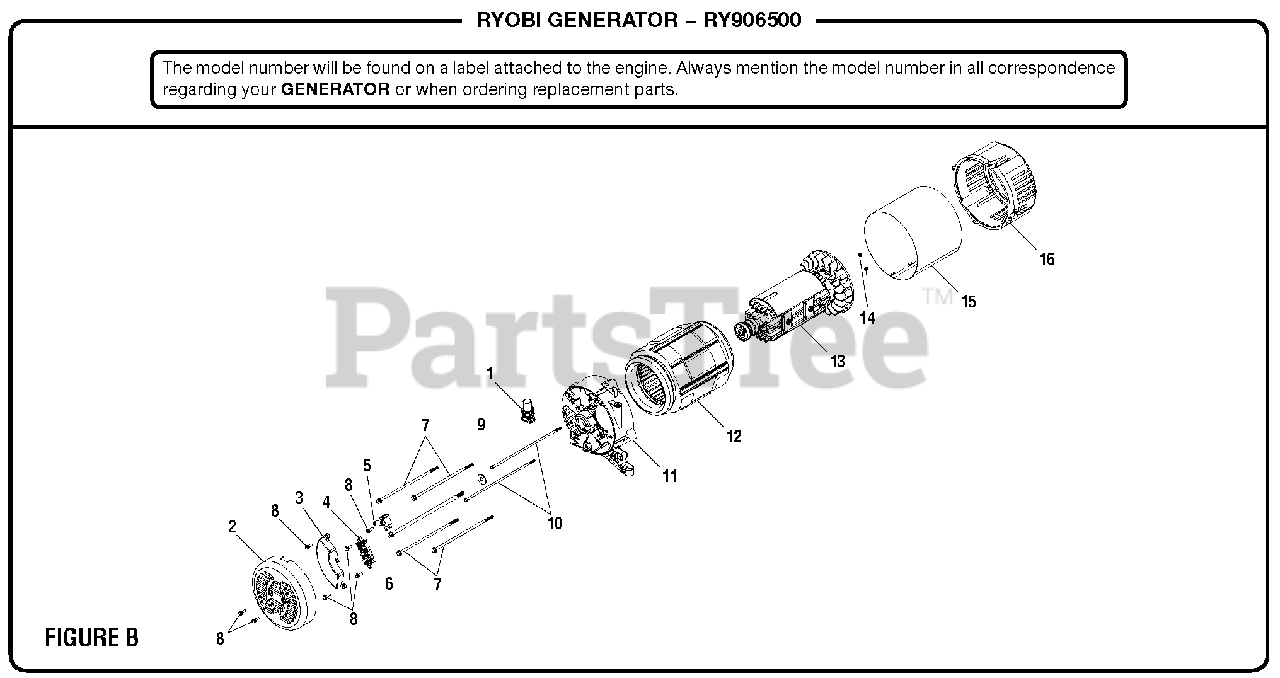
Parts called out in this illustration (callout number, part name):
1	Rubber Boot
2	Brush Cover
3	Automatic Voltage Regulator (5000 Watt)
4	Terminal Block
5	Brush Assembly
6	Rotor Bolt
7	Stator Bolt
8	Bolt (M5 x 16 mm, Hex Hd.)
9	Rotor Washer
10	Stator Bolt (M6 x 210 mm, hex hd.)
11	Bearing Housing
12	Stator Assembly
13	Rotor Assembly
16	Engine Adaptor
